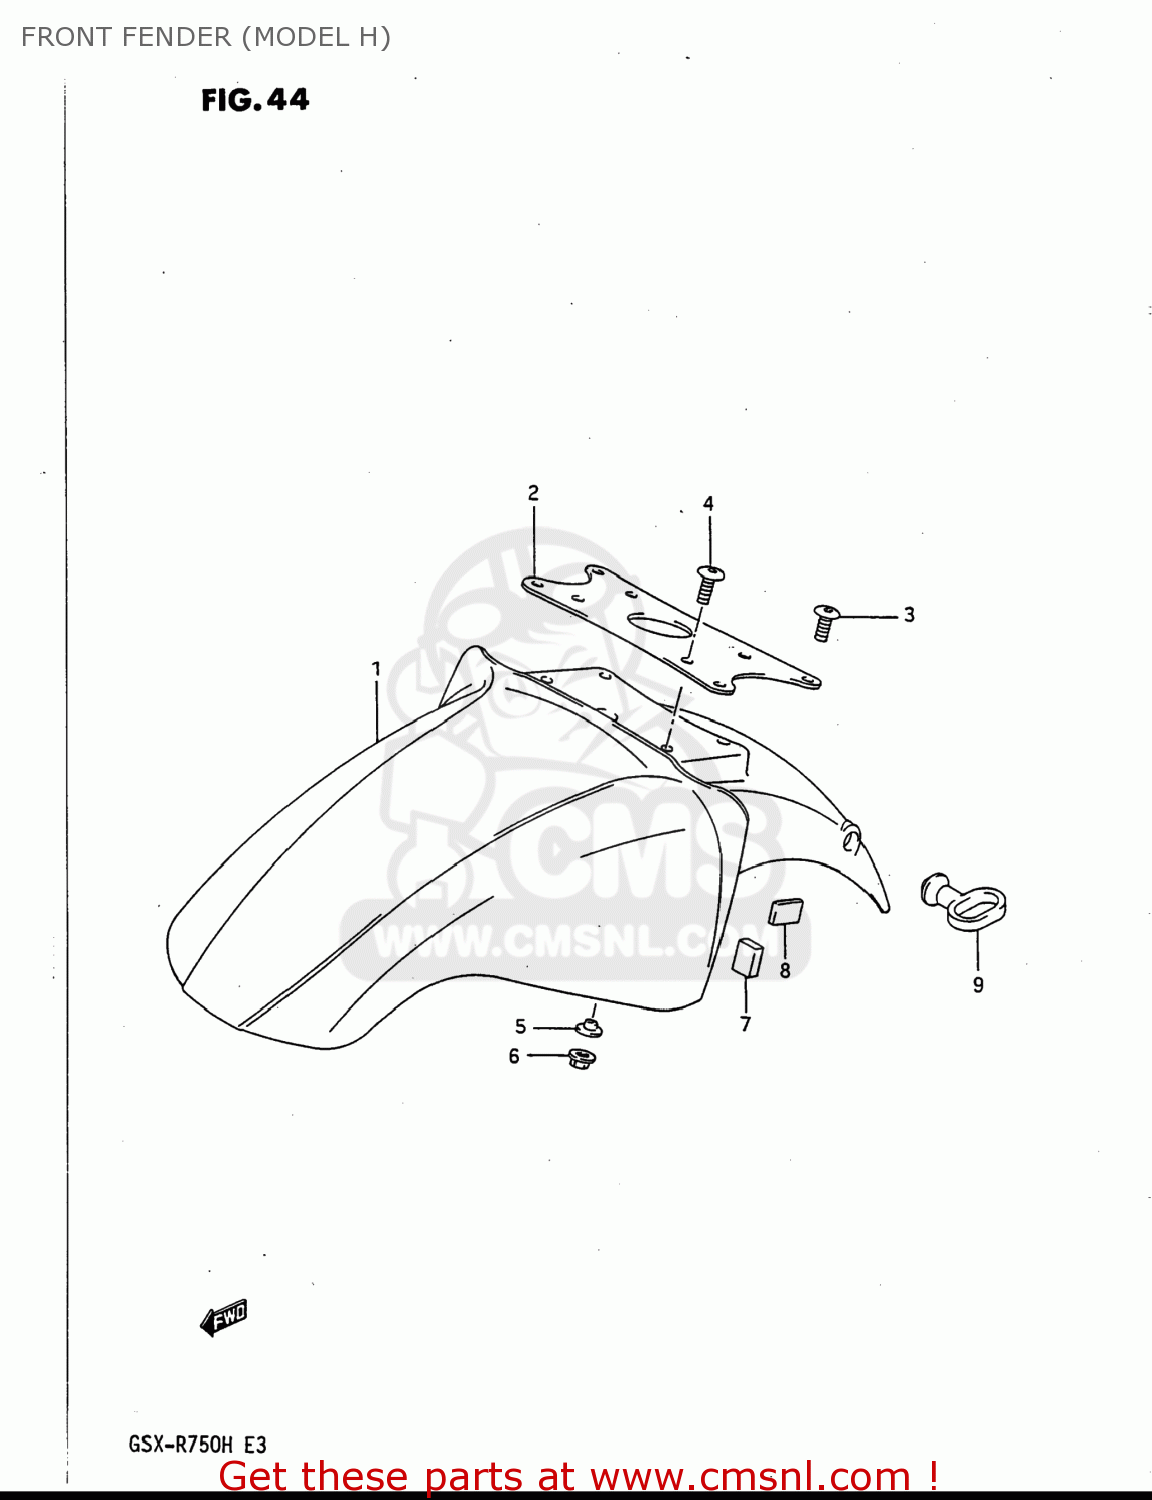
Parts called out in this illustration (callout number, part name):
1	FENDER,FRONT
2	BRACE,FRONT FENDER
3	SCREW(6X12)
4	SCREW(5X14)
5	WASHER
6	NUT
7	CUSHION,FRONT FENDER,S
8	CUSHION,FR FENDER SIDE
9	GUIDE,CABLE
